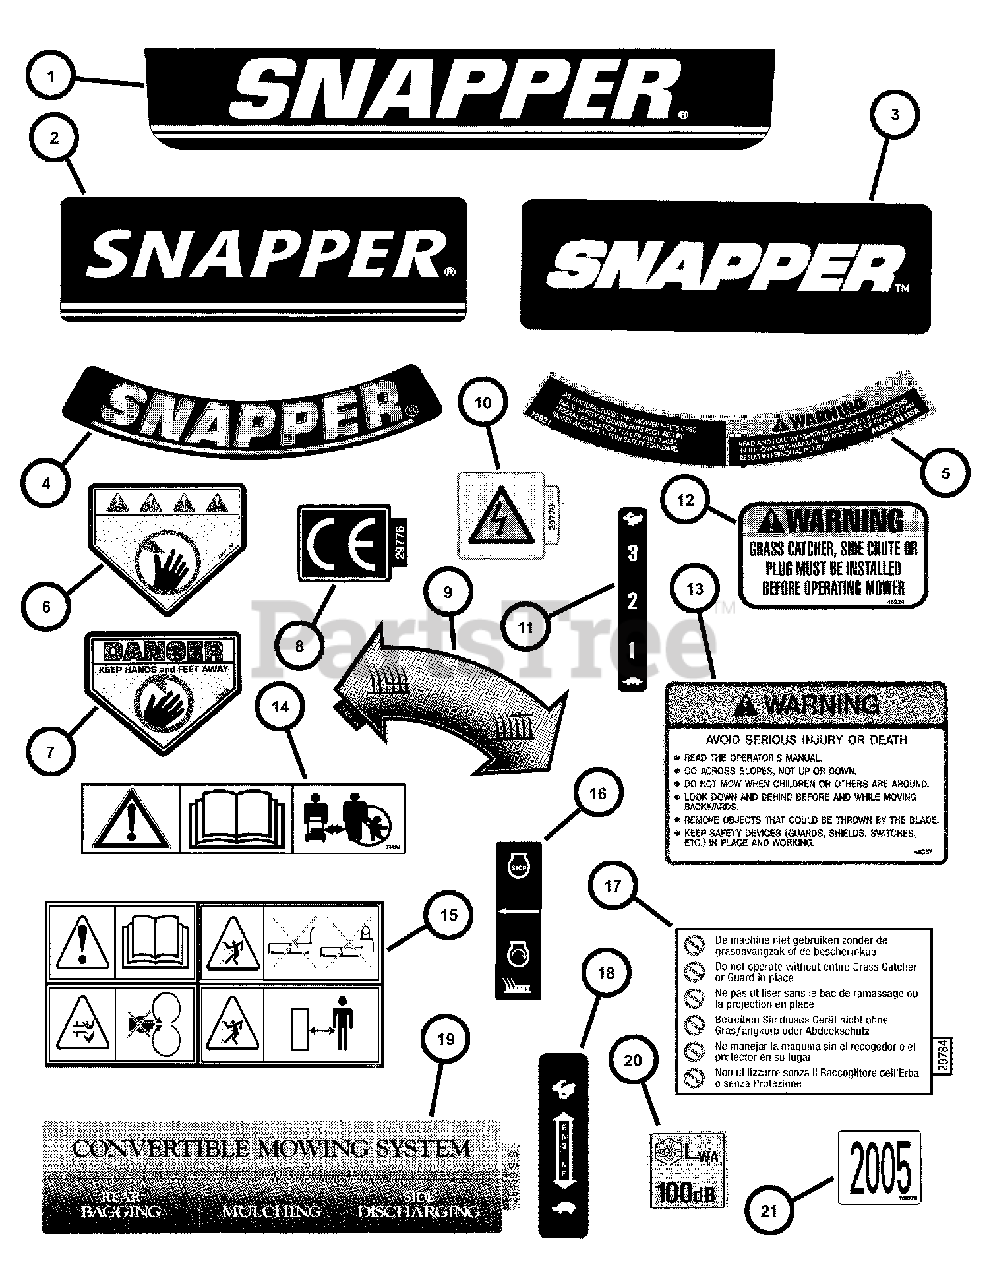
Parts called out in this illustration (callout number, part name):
1	DECAL, SNAPPER Name Plate
2	DECAL, SNAPPER Control Panel
3	DECAL, SNAPPER, Panel
4	DECAL, SNAPPER
5	DECAL, Warning (Deck)
6	DECAL, Warning (International Symbol)
7	DECAL, Danger (Keep Hands and Feet Away)
8	DECAL, European Community (CE)
9	DECAL, Height Control Instruction (Euro)
10	DECAL, Spark Plug International Symbol
11	DECAL, Speed Shift- ELP, ECLP
12	DECAL, Chute Deflector (Cast)
13	DECAL, Warning 1997
14	DECAL, Caution Symbols
15	DECAL, Warning Euro Multi-Panel
16	DECAL, OPC Bail International Symbol
17	DECAL, Chute/International Warning
18	DECAL, Throttle Control, B&S
19	DECAL, Convertible Mower
20	DECAL, Noise, 100 dB (shown)
21	DECAL, 2005 Year of Manufacture
